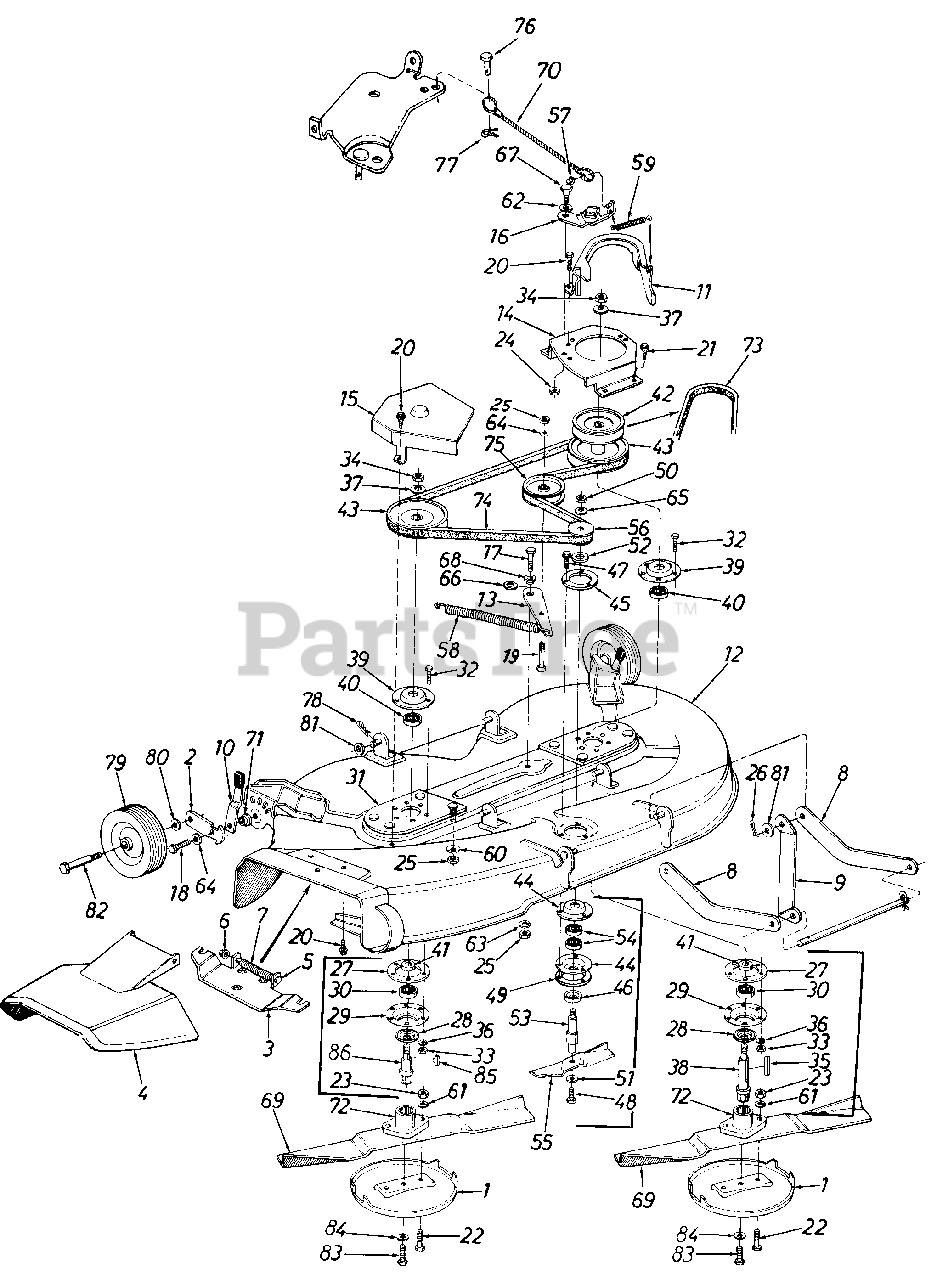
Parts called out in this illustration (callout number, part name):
1	Anti-Scalp Plate
2	Wheel Pivot Bar
3	Adapter
4	Chute Cover Ass'y.
5	Hinge Pin
6	Cap Speed Nut 1/4" Rod.
7	Torsion Spring
11	Belt Guard
12	44" DeckAssy.
13	Idler Bracket
14	Pulley Cover - L.H.
17	Hex Bolt 3/8-24 x 1.00"*
18	Hex Bolt 3/8-24 x 1.25" Lg.
19	Hex Bolt 3/8-24 x 1.50"*
20	Hex Wash. S-Tapp Scr. 1/4-20 x .50"
21	Hex Wash. Hd. Tapp Scr. 5/16-18 x .75" Lg.
22	Hex Bolt 5/16-24x 1.25" (Grade 5)
23	Hex Nut 5/16-24 Thd.*
24	Hex Cent. L.-Nut 5/16-18 Thd.
25	Hex Nut 3/8-24 Thd.*
26	Cotter Pin 3/32 Dia. x 1.00" Lg.*
27	Reinforcement Plate
28	Bearing Shield
29	Open Brg. Housing 1.85 I.D.
30	Ball Brg. .787 I.D. x 1.85 O.D. x.551
31	Spindle Mounting Plate Ass'y.
32	Hex Bolt 5/16-24 x 1.0"Lg.
33	Hex Nut- 5/16-24
34	Hex Jam Nut 5/8-18 Thd.
35	Square Key 3/16 x 2.25"Lg.
36	L.-Wash. 5/16 I.D.*
37	Bell. Wash. .630 I.D. x 1.25 x .090
38	44" Deck Blade Spindle
39	Bearing Housing 1.85 I.D.
40	Ball. Brg. .787 I.D. x 1.85 O.D. x .551
41	Spacer 1.0 O.D. x .790 I.D. .350 Lg.
42	5/8 "V" Pulley .79 I.D. x 5.75 O.D.
43	"V"- Pulley .79 I.D. x 6.50 O.D.
44	1-3/8" I.D. - Bearing Housing
45	Reinforcement Plate
46	Bearing Shield
47	Hex "B" Tap Scr. . 250 x . 750 Lg.
48	Hex Cl.-Scr. 3/8-24 x .88 Lg.
49	Reinforcement Plate
50	Hex Jam Nut 1/2-2 Thd.
51	Bell.-Wash. .400 I.D. x .88 O.D. x .060
52	Fl.-Wash. .635 x 1.04 O.D. x . 120"
53	6.5" Blade Spindle
54	Ball Brg. .62 I.D. x 1.30" O.D. x .44"
55	6.50" Blade
56	1/2" V-Pulley Half .625 I.D. x 2.25" O.D.
57	Cap Speed Nut 1/4" Rod.
58	Extension Spring .73 O.D. x 4.31 Lg.
59	Extension Spring .38 x 2.75" Lg
60	Bell.-Wash. .400 I.D. x .88 O.D. x .060
61	L.-Wash. 5/16" I.D.*
62	Spring Wash. .445 I.D. x .75 O.D. x .017
64	Bell.-Wash. .400 I.D. x 1.13 O.D. x .030
65	Bell.-Wash. .505 I.D. x 1.00 O.D. x .075
66	Spring Wash. .650 I.D. x .875 O.D. x .015 Thk.
67	Shld. Bolt .437 Dia. x .180
68	Shld. Spacer.625 I.D.
69	Mower Blade 21.88
70	Brake Cable Ass'y.
71	Shld. Spacer
72	Blade Adapter
73	"V"-Belt 1/2 x 56" Lg.
74	"V"-Belt 1/2 x 74"Lg.
75	Fl.-Idler w/Flanges 3.50 O.D.
76	Clevis Pin 1/4 Dia. x .53 Lg.
77	Intern. Cotter Pin 5/16" Dia.
78	Intern. Cotter Pin 1/2" Dia.
79	Deck Wheel 6.0 x 1.38
80	Bell.-Wash. .400 I.D. x .88 O.D. x .060
81	Fl.-Wash. .531 I.D. x .93 O.D. x .090
82	Shoulder Bolt 3/8-16 x 1.41
83	Hex Bolt 3/8-24 x .88" Lg.
84	L.-Washer 3/8 I.D.*
85	Sq. Key 3/16 x .75" Lg.
86	44" Deck Blade Spindle
